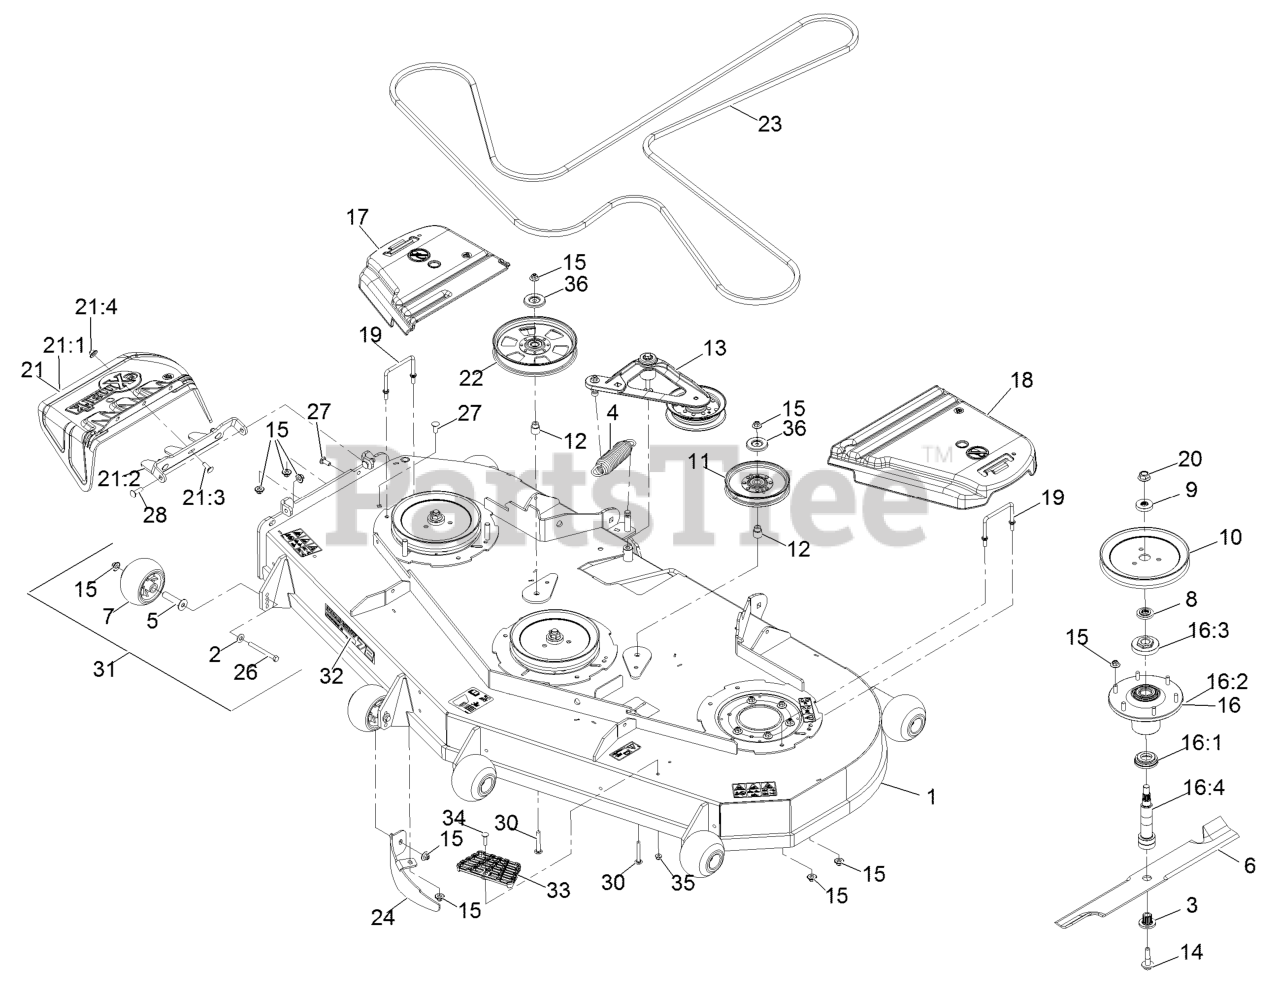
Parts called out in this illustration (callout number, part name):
1	ASM,DECK W/DECALS 724
2	WASHER-BELLEVILLE
3	BUSHING,SPLINED
4	SPRING-EXTENSION
5	AXLE, ROLLER
7	ROLLER-SCALP, ANTI
8	SPACER,SPLINED STEPPED
9	SPACER,SPLINED
10	SHEAVE,BLADE DRIVE 9.00
11	IDLER-PULLEY
12	BUSHING-IDLER
13	DECK IDLER ASM
14	SCREW,SEMS 1/2-20 X 2.19
15	Nut-Nyloc 3/8-16 Flg
16	ASM,SPINDLE HOUSING
16:1	GUARD,BOTTOM
16:2	ASM,CUTTER HOUSING
16:3	NUT, SPINDLE 7/8-14
16:4	SPINDLE,DOUBLE SPLINE
17	COVER-BELT, RH
18	COVER-BELT, LH
19	WIREFORM-COVER
20	NUT-FLANGE, CENTERLOCK
21	ASM,DISCHARGE CHUTE
21:1	CHUTE,DISCHARGE
21:2	BRACKET,DISCHARGE CHUTE
21:3	SCREW-CARR
21:4	Nut-Nyloc 3/8-16 Flg
22	PULLEY-IDLER, FLAT
23	BELT-V
24	BAFFLE-DOGLEG, LZ72
26	SCREW-HH 3/8-16 X 3 3/4 GR 8
27	SCREW-CARR
28	Bolt-Carriage 3/8-16 X 1 1/4
30	SCREW-CARR
31	KIT, ANTI-SCALP ROLLER
32	DECAL, 726
33	STEP-DECK
34	Bolt-Carriage 5/16-18 X 1 1/4
35	NUT-HF, NI
36	SHIELD-DUST
